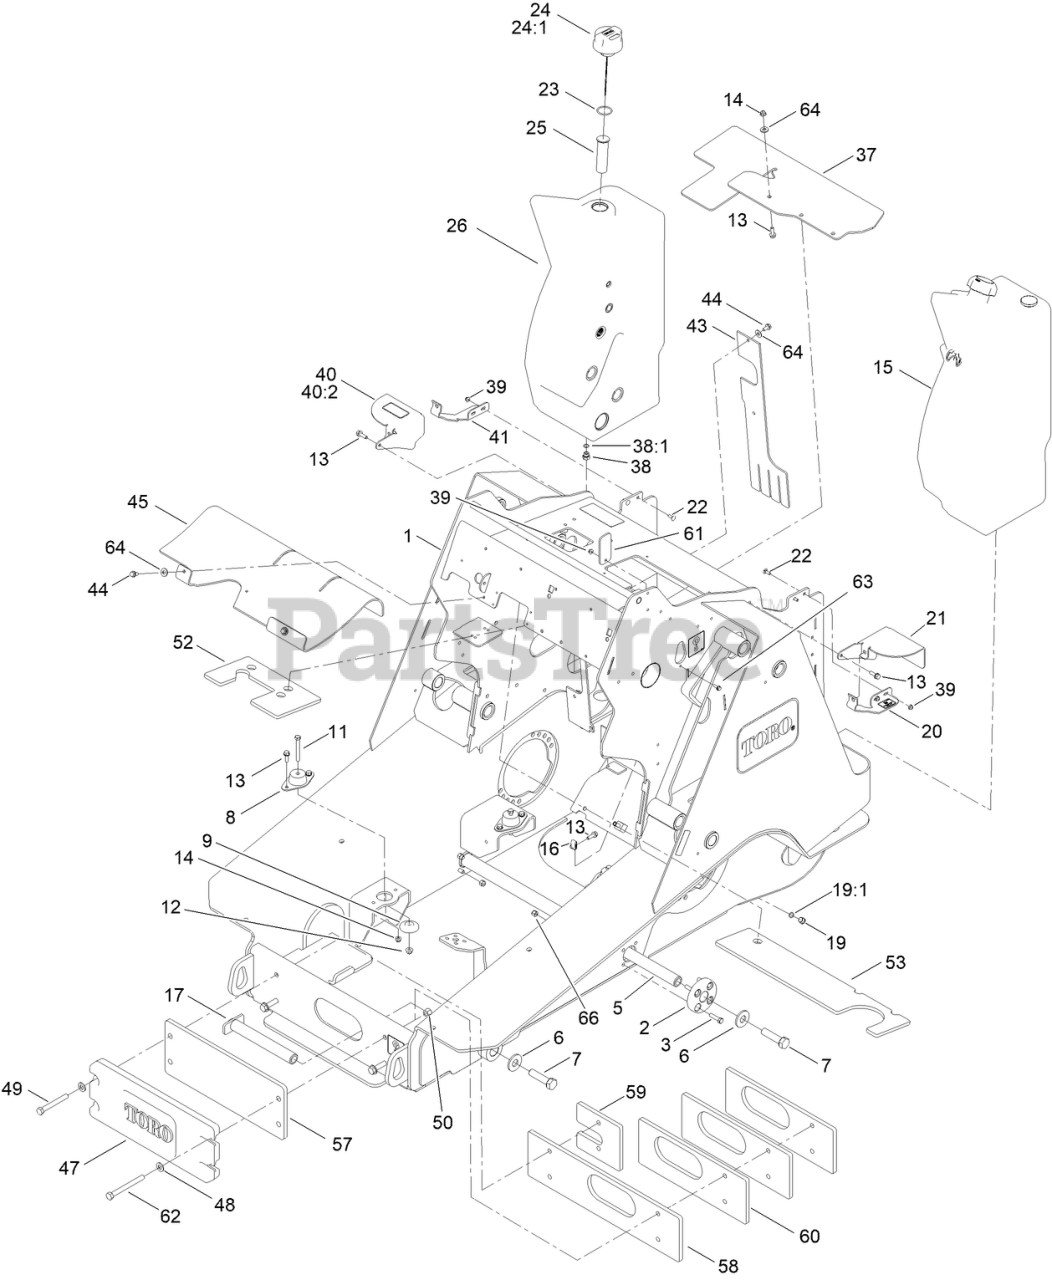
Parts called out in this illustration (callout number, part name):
1	MAIN FRAME ASM,
2	HUB-SHAFT
3	SCREW-HH
5	SHAFT-TRACK
6	WASHER
7	SCREW-HH
8	MOUNT-ENGINE
9	SUPPORT-ISOLATOR
11	SCREW-HH
12	NUT-HF, NI
13	SCREW-HHF
14	NUT-HF, NI
15	TANK ASM
16	NUT-CLIP, U
17	SHAFT-FRONT,TRACK
19	PLUG-HEX, HOLLOW
19:1	O-RING
20	BRACKET-TANK,(SERVICE)
21	BRACKET-TANK
22	BOLT-CARR
23	O-RING
24	CAP-HYDRAULIC, VENTED BREATHER
24:1	O-RING
25	FILTER-SCREEN
26	HYDRAULIC TANK W/INSERTS
37	BAFFLE-RUBBER
38	PLUG-HH
38:1	O-RING
39	NUT-HF
40	BRACKET-HYD TANK
40:2	DECAL-HYD FLUID
41	BRACKET-TANK, RH
43	BAFFLE-SIDE
44	SCREW-HWHTF
45	BAFFLE-CONSOLE
47	COUNTERWEIGHT-FRONT
48	WASHER-FLAT
49	SCREW-HH
50	NUT-LOCK, NI
52	FOAM-HEAT SHIELD
53	FOAM-HEAT SHIELD
57	PLATE-WEIGHT
58	PLATE-WEIGHT
59	PLATE-WEIGHT
60	PLATE-WEIGHT
61	COVER-RUBBER
62	SCREW-HH
63	SCREW-HHF
64	WASHER-FLAT
66	NUT-LOCK
